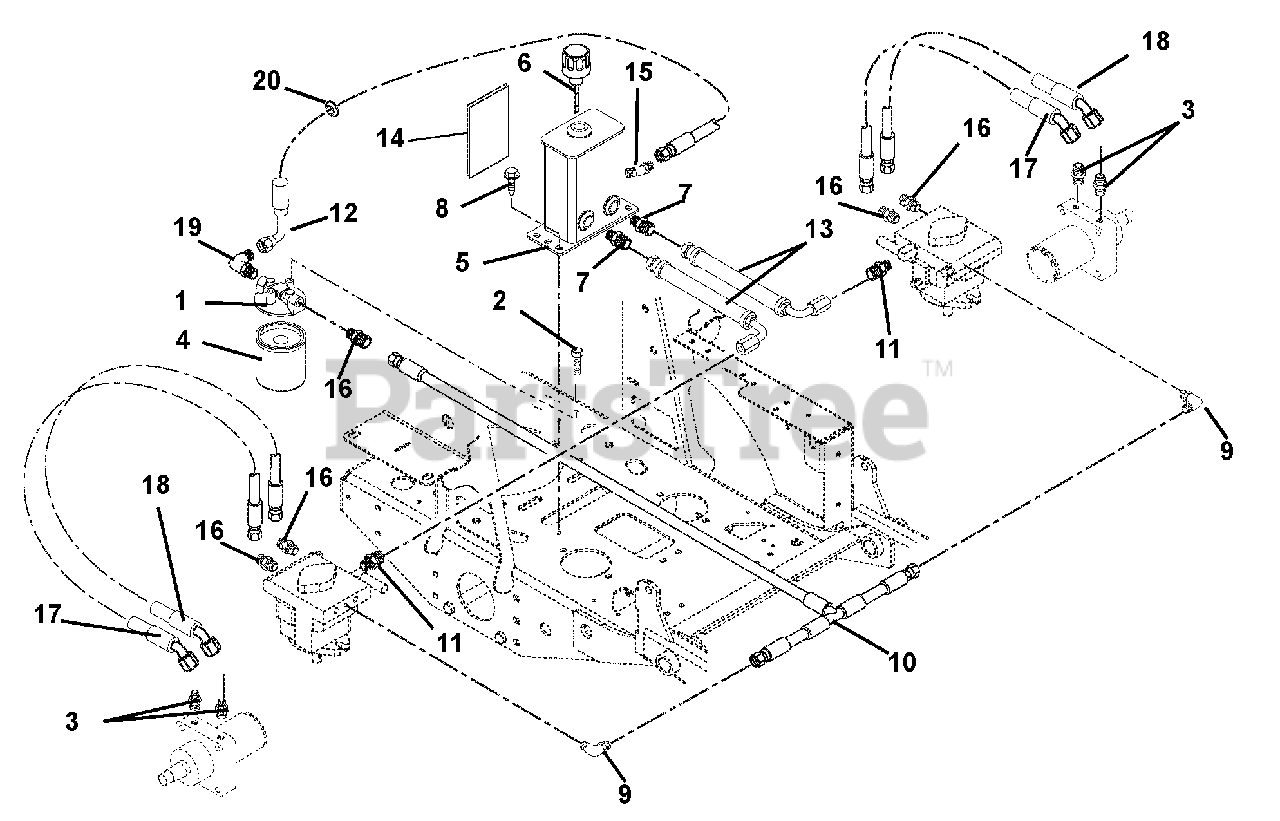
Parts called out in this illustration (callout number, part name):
1	Head, Filter
2	Bolt, Hex .25-20 x .50 Grade 5
3	Adapter, Hydraulic
4	Oil Filter
5	Weldment, Formed Hydraulic Tank - 3 Port (SN 003000 and up)
6	Breather Dipstick
7	Fitting, Hydraulic Straight M8O-M4F
8	Screw, Tapping .38-16 x .50 Hex Washer Head
9	Fitting, Hydraulic (6C5OLO)
10	Hose, Hydraulic .50 to .38 Tee Assembly
11	Fitting, Hydraulic (4-6 F5OLO)
12	Hose, Hydraulic .50-11-OK F8FO-F8F9 (SN 003000 and up)
13	Hose, Hydraulic
14	Shield, Heat 5.50 x 4.50
15	Adapter, Face Seal 8x8 .50 O-Ring 8 F6OLO - Steel (SN 003000 and up)
16	Fitting, Hydraulic
17	Hose, Hydraulic .50-11-3K
18	Hose, Hydraulic .50-12-3K
19	Fitting, Hydraulic EL M8F-M80
20	Grommet, 1.25ID x 1.50OD
